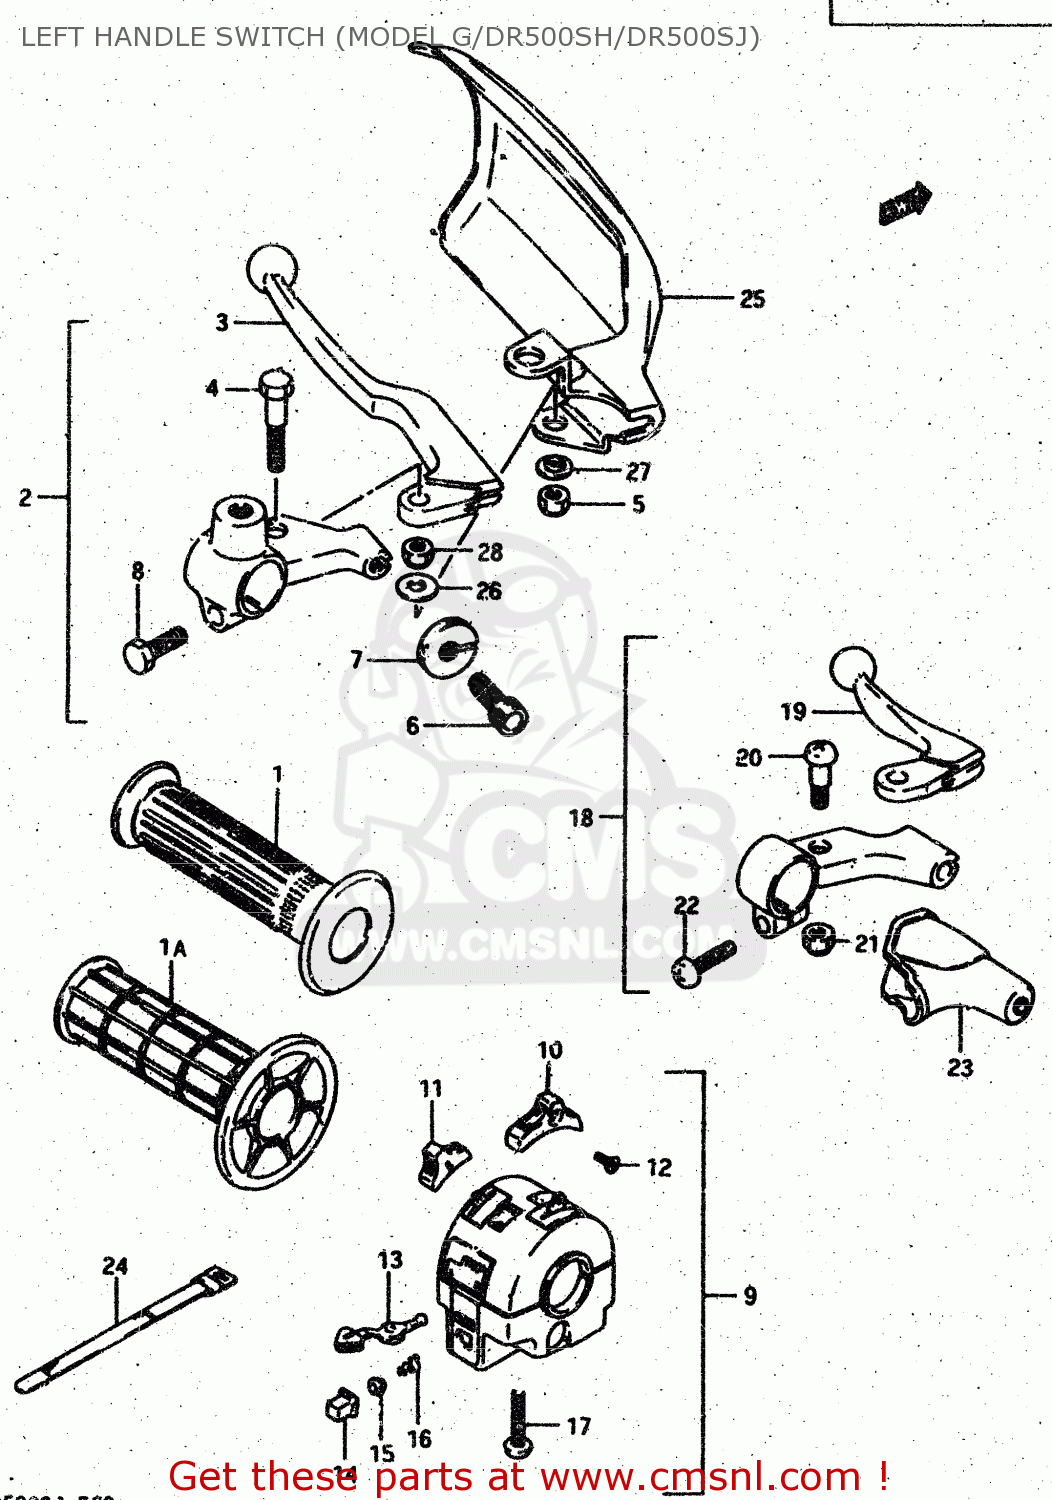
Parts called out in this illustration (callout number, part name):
1	GRIP,L
1A	GRIP,LEFT
2	LEVER ASSY,CLUTCH
3	LEVER,CLUTCH
4	BOLT,LEVER SET
5	NUT
6	ADJUSTER,CABLE
7	NUT,CABLE ADJUSTER LOCK
8	BOLT
9	SWITCH ASSY,HANDLE LH
10	KNOB,LIGHTING SWITCH
11	KNOB,DIMMER SWITCH
12	SCREW
13	KNOB,TURNSIGNAL
14	BUTTON,HORN
15	CONTACT
16	SPRING
17	SCREW
18	LEVER ASSEMBLY,DECOMPRESSION
19	LEVER,DECOMP
20	BOLT,LEVER
21	NUT
22	SCREW
23	COVER,DECOMP LEVER DUST
24	CLAMP(L:120)
25	COVER,KNUCKLE,L
26	WASHER(6.5X16X1.2)
27	WASHER
28	NUT 6MM
